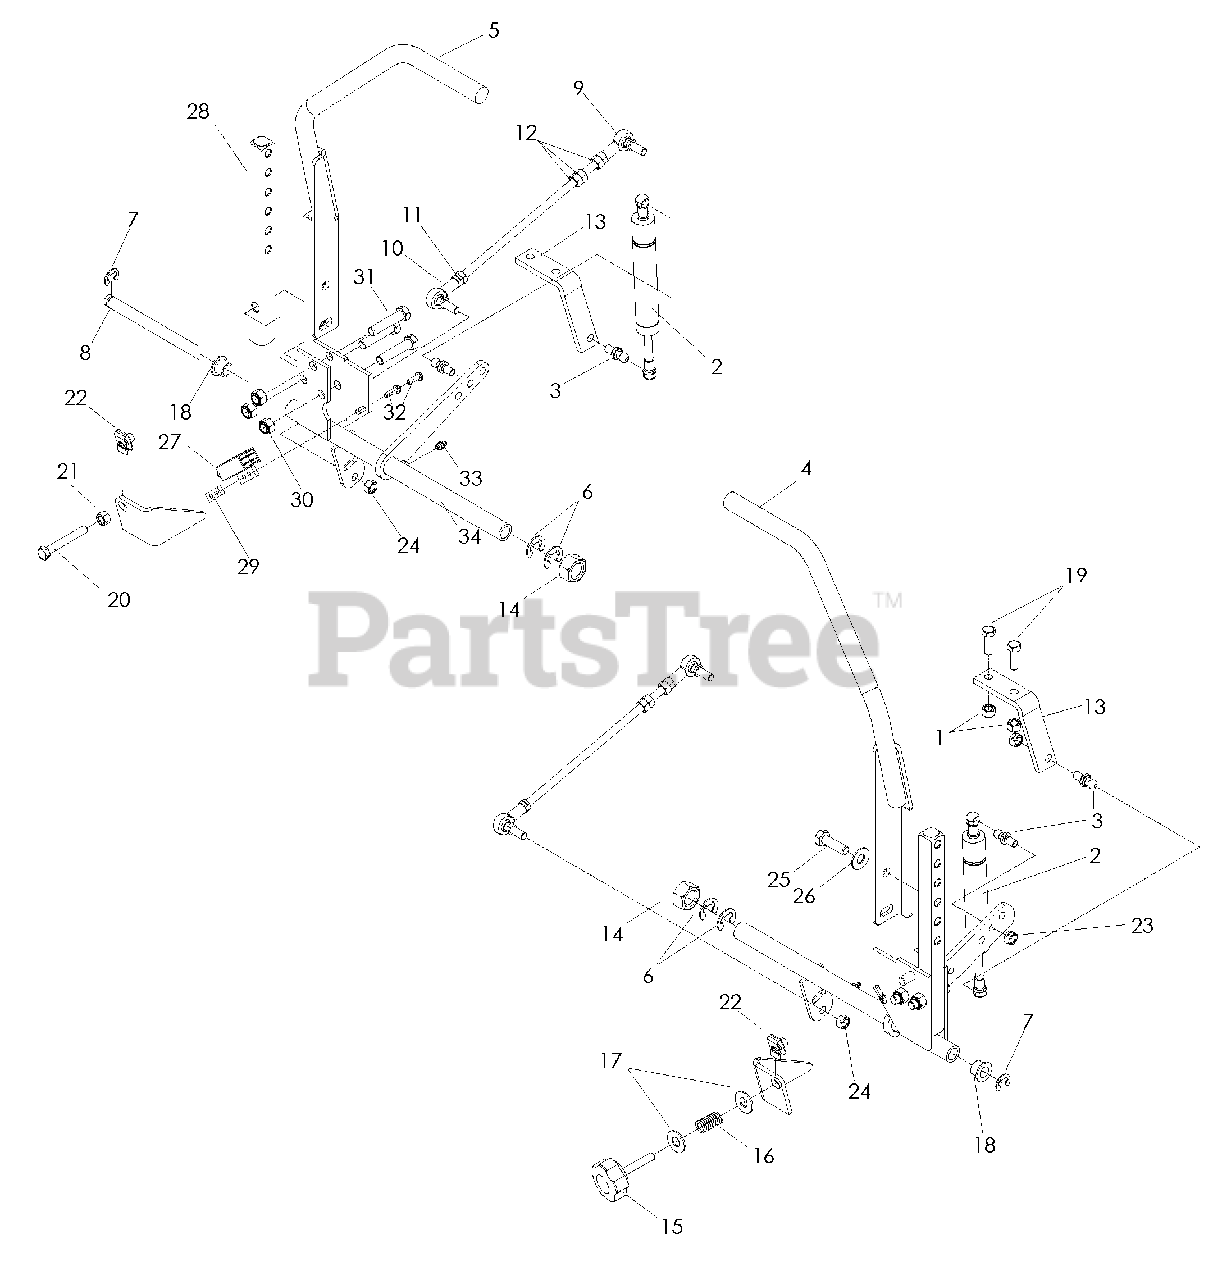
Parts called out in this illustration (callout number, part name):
1	Nut 5/16-18 Hex Nyloc
3	Stud, 10Mm Ball
4	Control Wldmt Lt
5	Control Wldmt Rt
6	E-Ring 5/8
7	E-Ring 1/2
8	Control Shaft
9	Spherical Rod End Lh
10	Spherical Rod End Rh
11	Nut 5/16-24 Hex Jam Lh
12	Nut 5/16-24 Hex
13	Bracket, Dampener
14	Nut 3/4-16 Hex
17	Washer 5/16 Std Flt
19	Hcs 5/16-18 x 1
20	Hcs 5/16-18 x 1 3/4 Tpblt
21	Nut 5/16-18 Hex
22	Retainer, 5/16-18 U-Type
23	Nut 5/16-18 Hex Ctrlk
24	Nut 5/16-24 Nyloc
25	Hcs 3/8-16 x 1
26	Washer 3/8 Spring
27	Switch, Interlock 2P
28	Arm, Control Shaft
29	Tapped Plate
30	Nut 3/8-16 Hex Nyloc
31	Hcs 3/8-16 x 1 3/4
32	Screw 10-24 x .625
33	Zerk
34	Control, Drive, Lt
